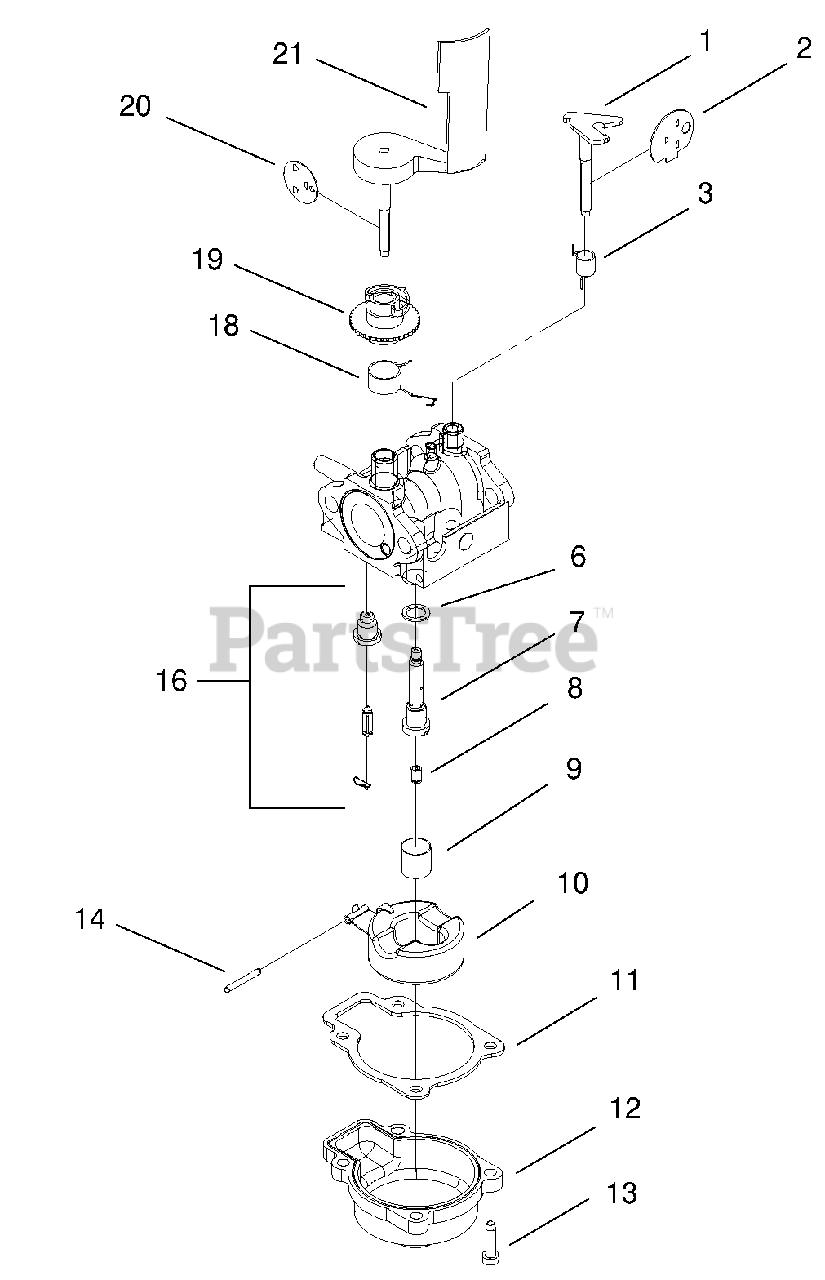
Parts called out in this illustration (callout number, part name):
1	SHAFT-CHOKE
2	DISC-CHOKE
3	SPRING-CHOKE
8	JET-MAIN (77.5)
9	FILTER-FUEL
10	FLOAT & ARM ASM
12	CHAMBER-FLOAT
13	SCREW-HH
14	PIN-STRAIGHT
16	VALVE/SEAT-FLOAT
18	SPRING-THROTTLE
19	COLLAR-ADJUST, AIRVANE
20	THROTTLE-DISC E
21	AIRVANE AND SHAFT ASM
